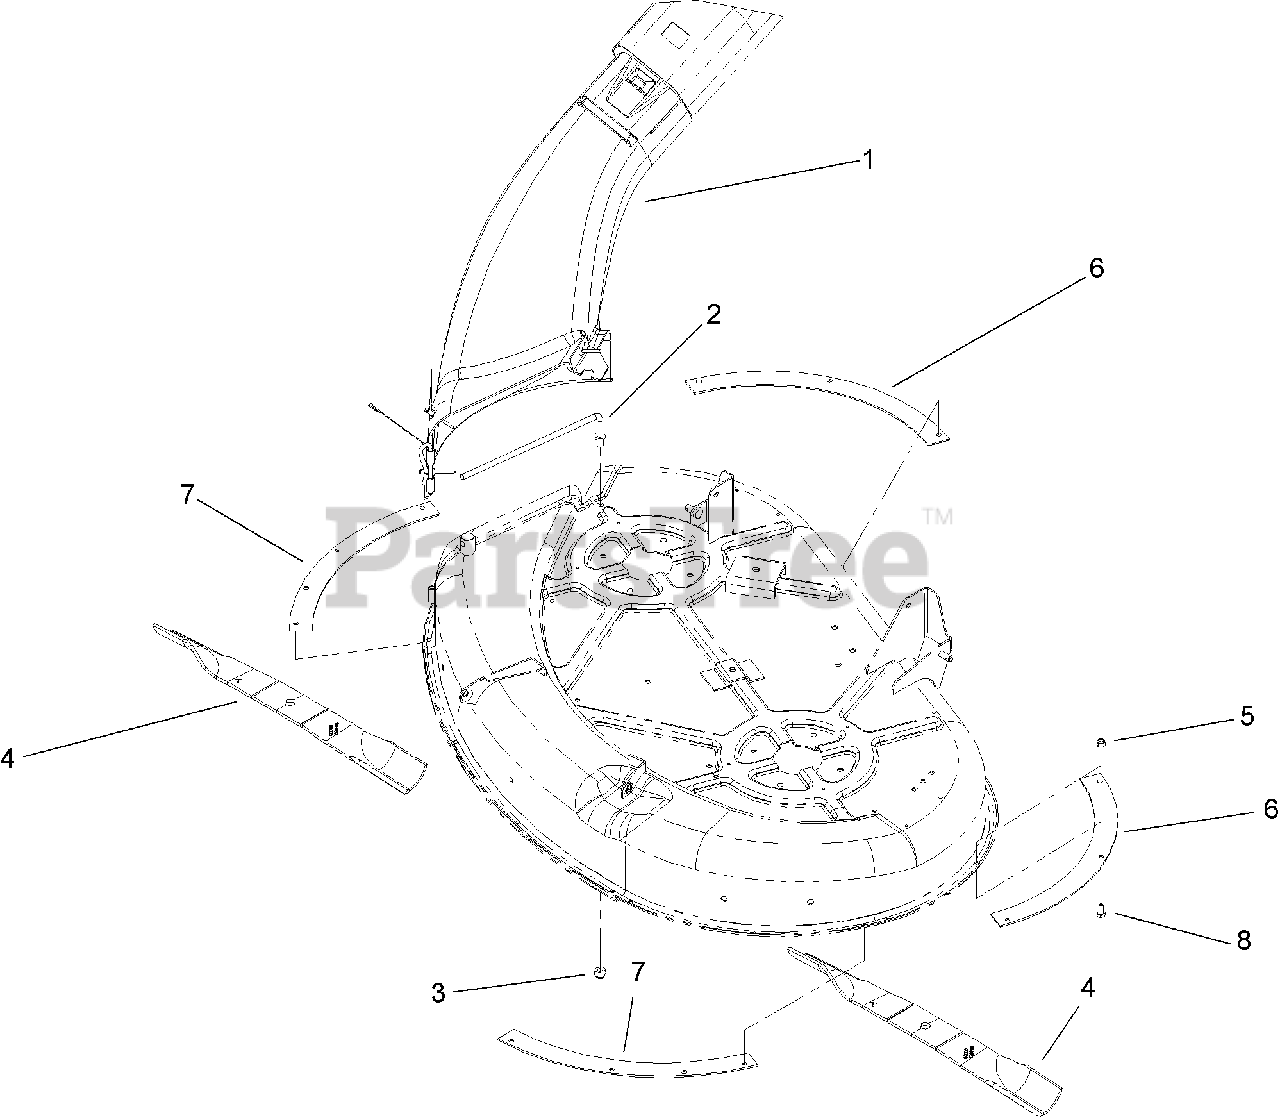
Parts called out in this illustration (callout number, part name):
1	42 INCH BAGGER CHUTE ASM
2	ROD-PIVOT
3	NUT-LOCK, NI
4	BLADE-21.6 INCH
5	NUT-LOCK, NI
6	RING-BLOW OUT, SIDE
7	RING-BLOW OUT, SIDE
8	SCREW-HH
